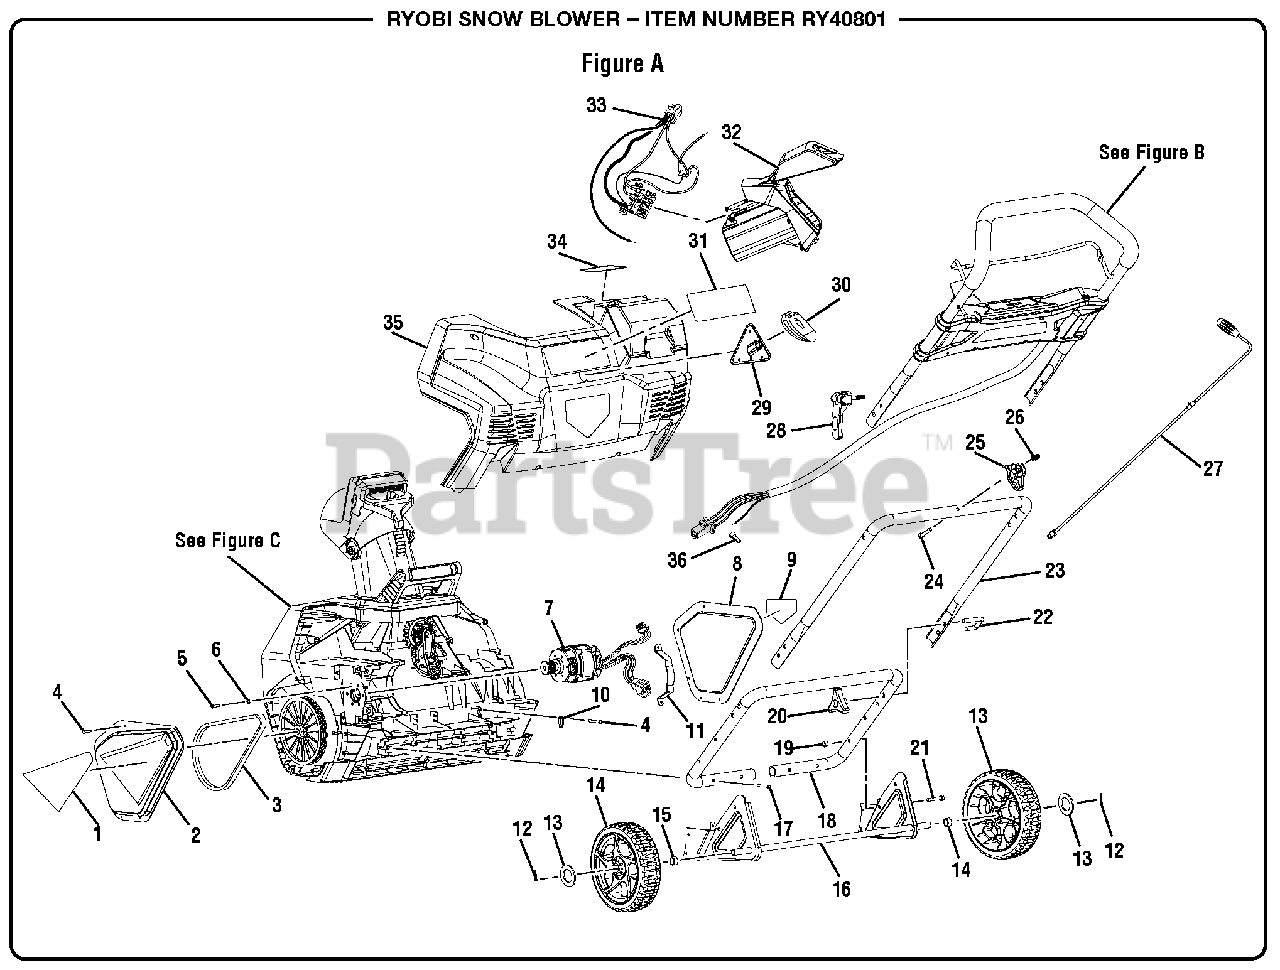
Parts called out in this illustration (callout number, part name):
1	Brushless Motor Label
2	Left Side Cover
4	Screw (M4.2 x 16 mm)
5	Screw (M5 x 8 mm)
6	Washer (M5)
8	Right Side Cover
9	Hands and Feet Label
11	Motor Plate
13	Washer (ID13.5 x 1.5t)
14	Wheel Assembly
16	Axle Assembly
17	Screw (M5 x 35 mm)
18	Lower Handle
21	Bolt (M6 x 35 mm)
23	Middle Handle
24	Screw (M6 x 35 mm)
27	Rod Assembly
28	Cam Lock Assembly
31	Warning Label
32	Battery Compartment
33	Battery Connector Harness
34	Lithioum-ion 40V Label
35	Rear Housing
36	Wire Connector
